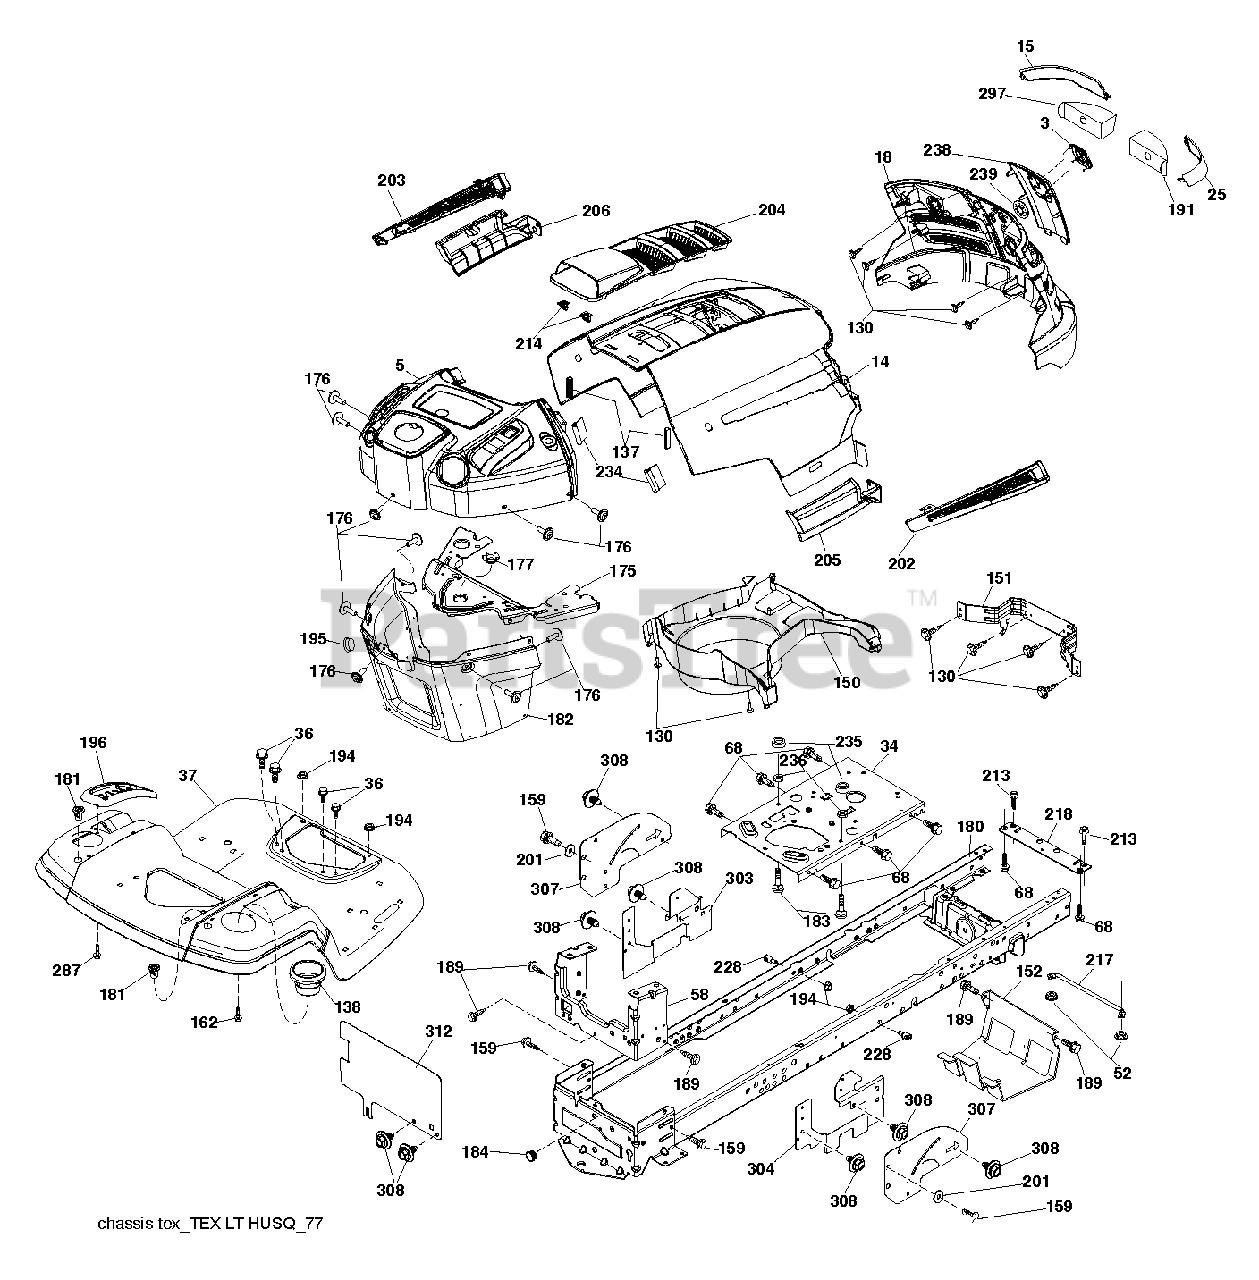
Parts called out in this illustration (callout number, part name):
3	LOGO.HUSQ.GT.LT.CROWN.H
5	DASH.UP.HU.LT.CBL.CLTCH.CHG.PT
14	HOOD.HUSQVARNA.LT.ORANGE
15	LENS.HUSQVARNA LT.RH
18	GRILLE.SVC.HUSQVARNA.GREY
25	LENS LH
34	PLATE.ENGINE.WELDED.CHASSIS
36	SCREW 5/16"
37	FENDER.TLT.PDL.CNTRL.W/CPH.ORG
52	LOCKNUT
58	DRAWBAR UPPER 2PC SMALL FENDER
68	SCREW LT
130	SCREW.#10 X 0.750.BOS
137	BUMPER DASH
138	HOLDER.CUP.LT.GREY
151	BRACKET PIVOT
152	SHIELD.BROWNING.W/TEX
159	SCREW, 3/8-16X3/4
162	SCREW.HI-LO.CONSOLE
175	CROSSMEMBER
176	SCREW.#10-24X5/8.RN.QU
177	BUSHING STEERING
180	CHASS.WLDMNT.TL.12GA/2P.48/54
181	BUSHING.MNT.FEND.CRGO.TEX.49
182	DASH.LOWER.PREDATOR LT
183	BOLT.5/16-18X1-1/4 FULL THD
184	PLUG.DEMO.625
189	SCREW
191	INSERT.REFLECTIVE.RH.
194	NUT LOCK HEX FLANGE 5/16-18
195	PLUG.TEX.DASH.SVC.MINDER.GREY
196	DECKLFT.CONSOL FULL ASSM GREY
201	WASHER
202	VENT.SIDE.HUSQVARNA.LT.RT
203	VENT.SIDE.HUSQVARNA.LT.LFT
204	SUBASM.TOP.VENT.HUSQ.LT
205	SKIRT.SIDE.HUSQVARNA.LT.RT
206	SKIRT.SIDE.HUSQVARNA.LT.LEFT
213	BOLT
214	CLIP.RETAINER.TINNER.
217	ROD.PIVOT.HOOD
218	X-PIECE.HOOD.STOP.NON/
228	STUD.FASTNER.W/ANTI-ROTATE
234	BUMPER.HOOD.TEX.HUSQVARNA
235	SPACER FENDER
236	NUT.CENTERLOCK.5/16-
238	TRIM.HUSQ LT.668
287	SCREW 1/4X20
297	INSERT REFLECTIVE
303	SHIELD.LOWER.LH/LT/GT/BLK.EDIP
304	SHIELD.RH.LOW.LTGT.NO
307	SHIELD.UPPER.LT.GT.ISO
308	BOLT, 5/16-18 X 1 3/4
312	SHIELD.DRAWBAR.LT.FRNTTANK.431
